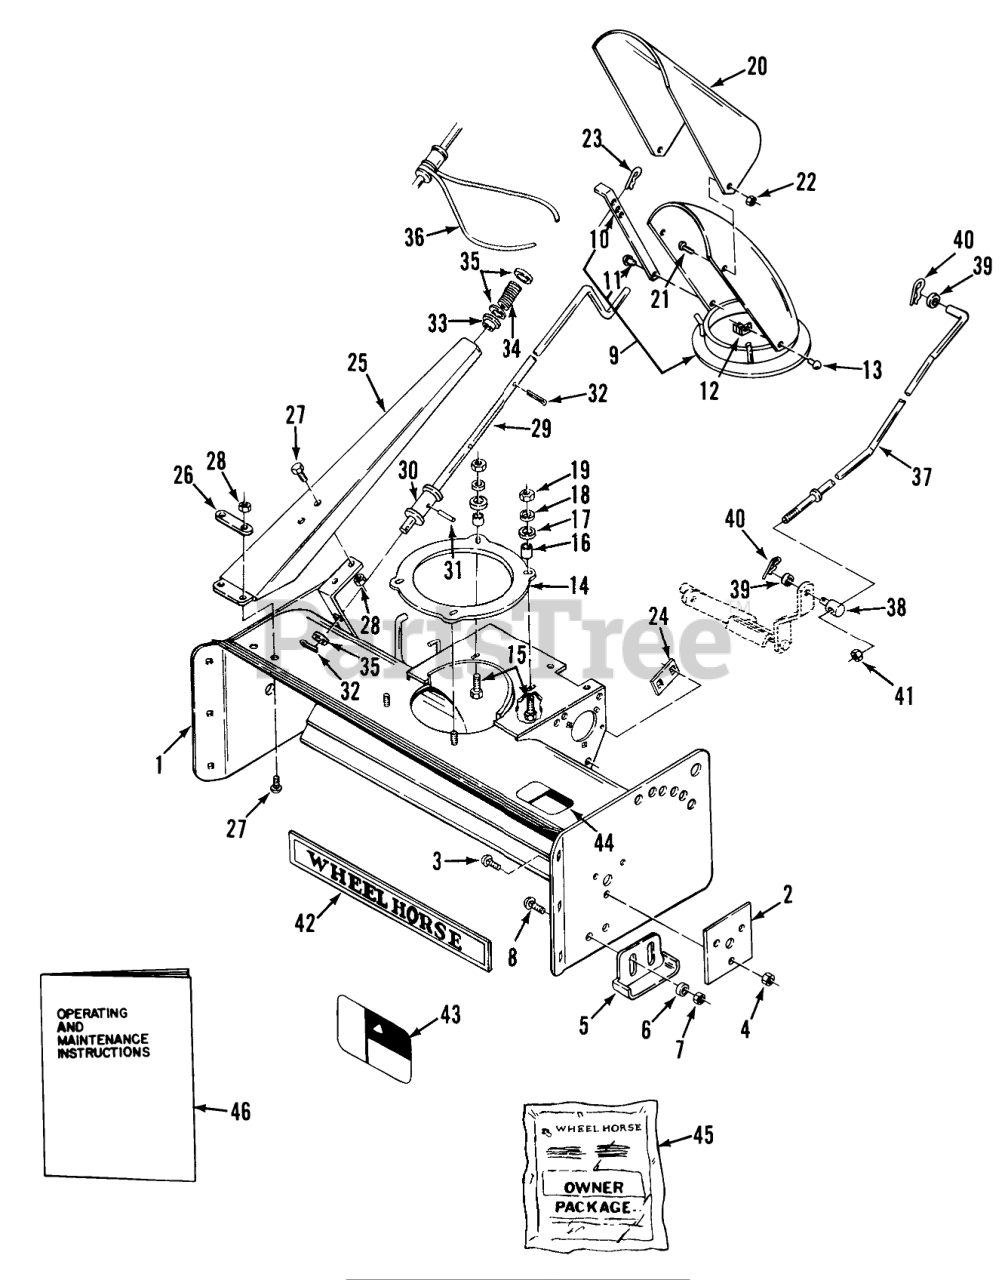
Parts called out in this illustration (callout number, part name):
1	ASSY WRAPPER R
2	Plate
3	CARRIAGE BOLT -4
4	Nut
5	Skid
6	Washer
7	Nut
8	Bolt
9	Shroud (includes items 10 & 11)
10	ARM R
11	RIVET
12	CLAMP
13	RIVET-4
14	COLLAR
15	Bolt
16	SPACER
17	WASHER
18	Washer
19	NUT
20	Deflector
21	MACH. SCREW
22	Nut
23	Hairpin
24	STRAP
25	Crank Support
26	Bar-Reinforcing
27	Bolt
28	Nut
29	CRANK R
30	TUBE R
31	ROLL PIN 1/4 X 1-1/4
32	Pop Rivet
33	NYLINER BUSHING
34	SPRING-COMPRESSION
35	Washer
36	CABLE
37	ROD LIFT
38	TRUNION
39	Washer
40	Hairpin Cotter
41	Nut
42	DECAL WHEEL HORSE
43	DECAL DANGER
44	DECAL DANGER
45	Loose Parts Package
